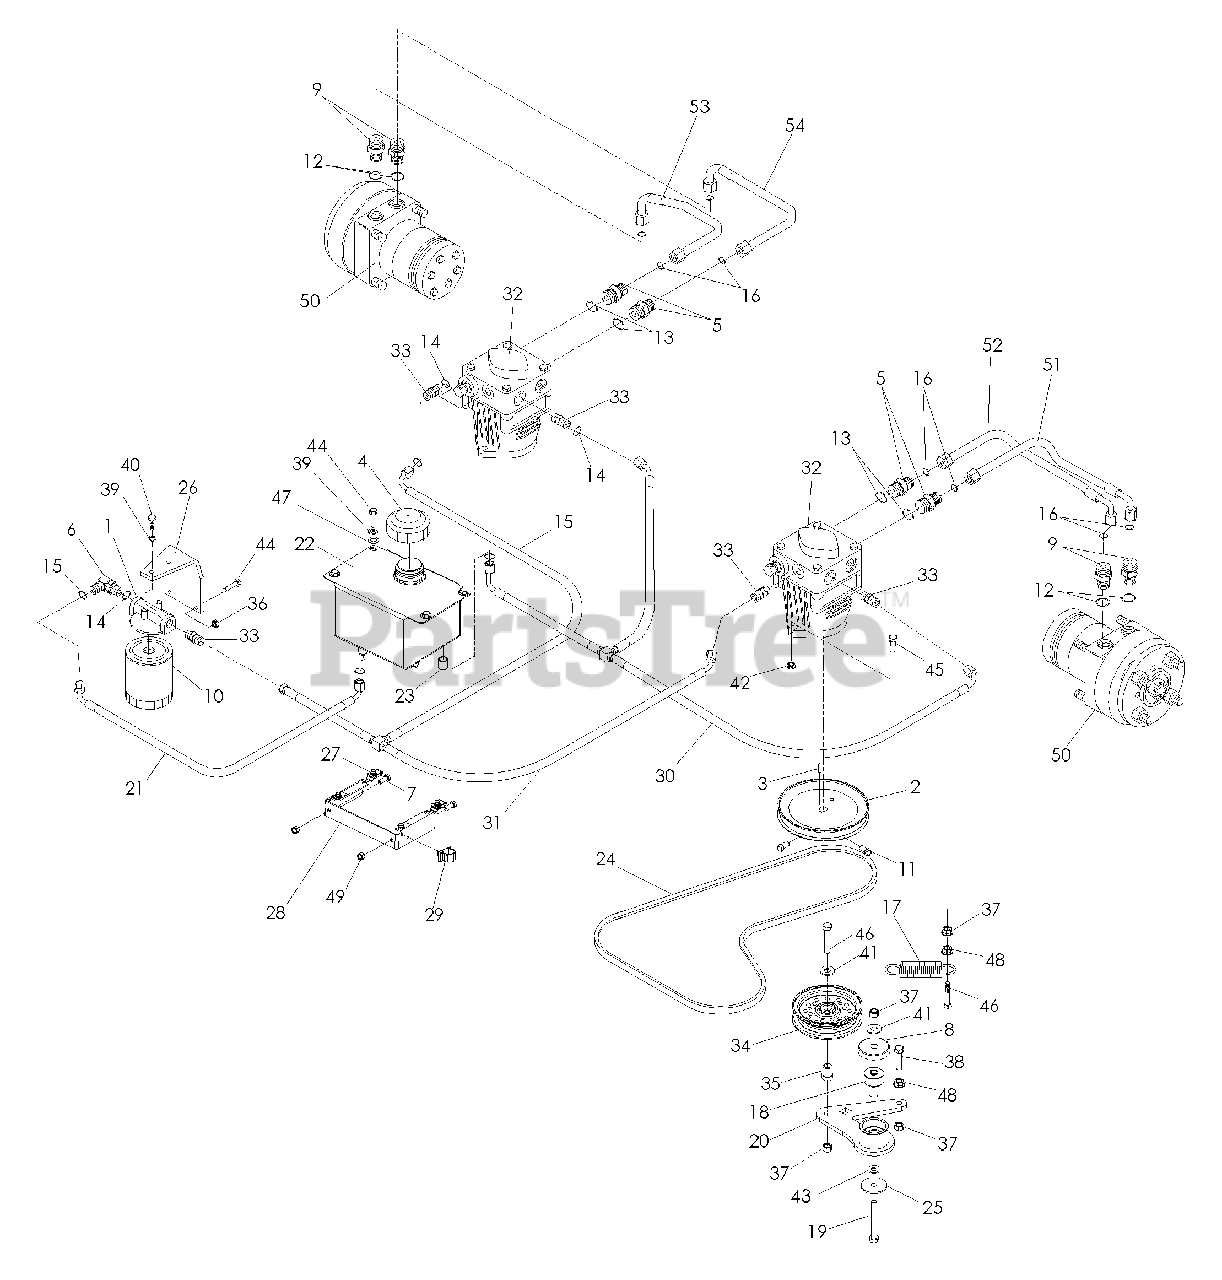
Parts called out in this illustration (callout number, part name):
1	FILTER HEAD
3	KEY, 5MM SQ x 30MM
4	CAP, HYDRO RESERVOIR
5	FITTING, F6400-8-8-0
6	FITTING, F6801-6-6-0
7	HCS 5/16-18 x 3/4
8	SHIELD, DUST 1/2 ID
9	STRAIGHT FITTING
10	FILTER ELEMENT
11	SCREW 5/16-18 x 5/8
12	O RING 3/4
13	O RING 1/2
14	O RING 3/4
15	O RING FLARE 3/8
16	O RING FLARE 1/2
17	SPRING, EXTENSION
18	BEARING, PIVOT
19	HCS 3/8-16 x 3
20	ARM, IDLER
24	PUMP BELT
25	WASHER 3/8 SPECIAL
26	OIL FILTER BRACKET
27	RETAINER, U TYPE
28	TANK MOUNT
29	CLIP, WIRE
30	T ASSEMBLY
31	T ASSEMBLY
32	10CC PUMP w/RTN’S
33	HYDRAULIC FITTING
34	PULLEY, IDLER
35	BUSHING, FLANGE IDLER
36	NUT 1/4-20 HEX NYLOC
37	NUT 3/8-16 HEX NYLOC
38	HCS 3/8-16 x 1 1/2
39	WASHER, 1/4 SPLIT LOCK
40	HCS 1/4-20 x 5/8
41	WASHER 3/8 FLAT STD
42	NUT 3/8-16 CENTERLOCK
43	WASHER 3/8 SAE FLT
44	HCS 1/4-20 x 3/4
45	HCS 3/8-16 x 1 WHIZLK
46	HCS 3/8-16 x 2
47	WASHER 1/4
48	NUT 3/8-16 WHIZLK
49	NUT 5/16-18 HEX NYLOC
50	WHEEL MOTOR
50	WHEEL MOTOR MODELS iZ4217, iZ4819, iZ4217C
51	HYDRAULIC LINE
52	HYDRAULIC LINE
53	HYDRAULIC LINE
54	HYDRAULIC LINE
